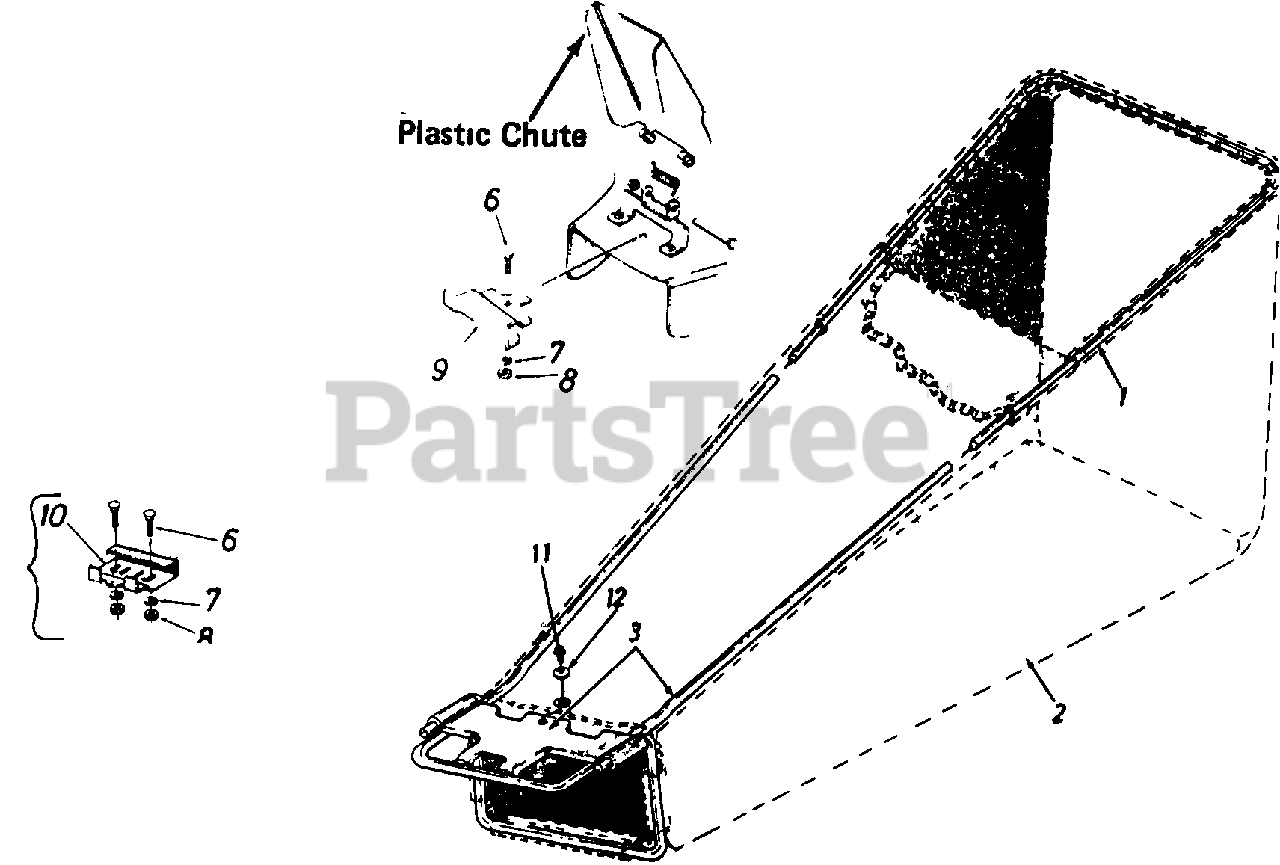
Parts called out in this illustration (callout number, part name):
2	Grass Catcher Bag
3	Fram-Lower
6	Carriage Bolt
7	Lock Washer 1/4" I.D.*
8	H ex Nut 1/4-20 Thd.*
9	Adapter Plate
10	Adapter Plate
11	Self-Tap Scr. 1/4" x 1/2" Lg.
12	Bell-W ash. 1/4" I.D.
